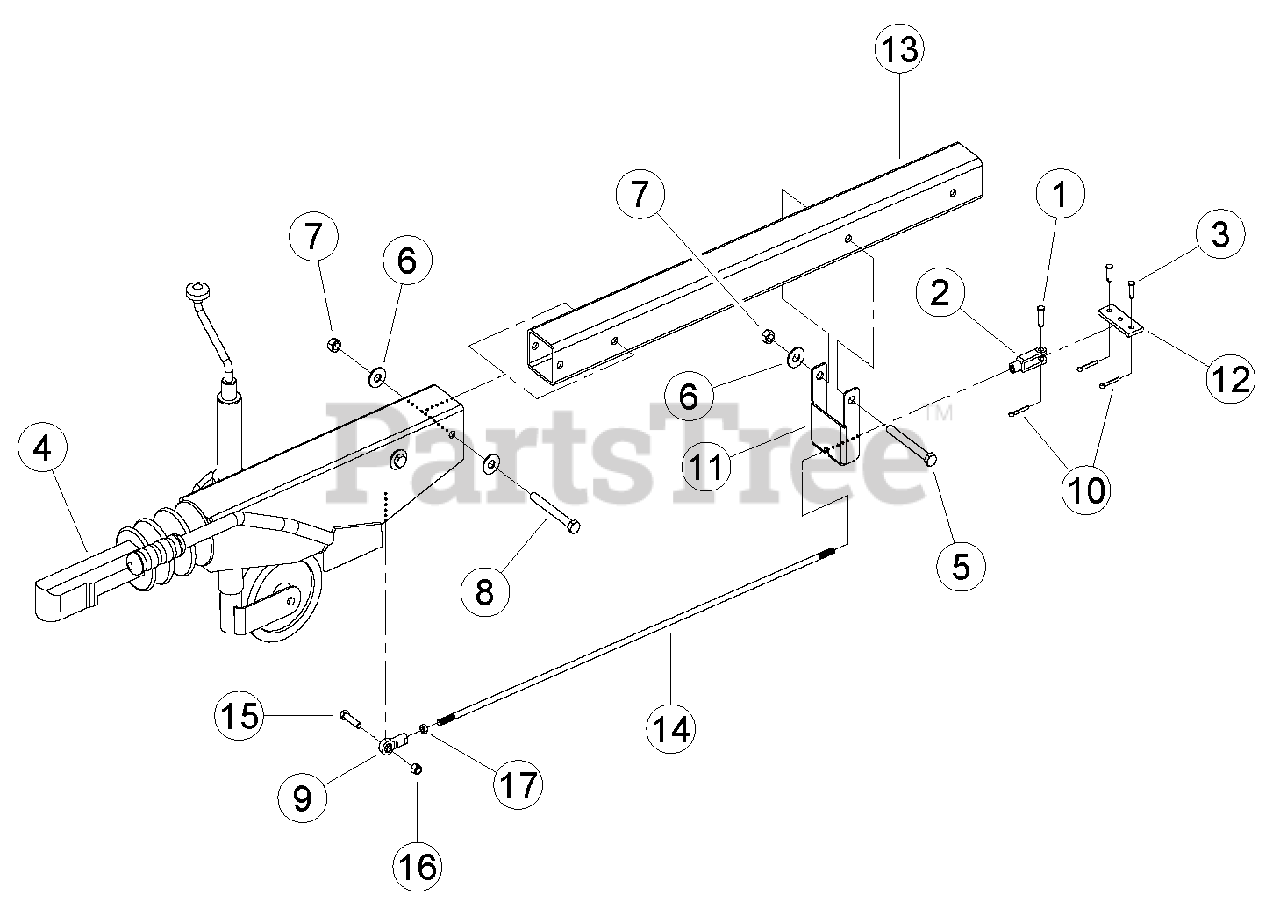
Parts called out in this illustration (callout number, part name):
1	PIN, 3/8 X 1-1/4 CLEVIS ZP
2	CLEVIS, ADJ. ROD END 3/8-24 UNF
3	PIN, 5/16 X 1 CLEVIS
4	COUPLING, SURGE W/JOCKEY WHEEL
5	BOLT, 1/2 X 4-1/2 HEX HD GR5 NC ZP
6	WASHER, 1/2 FLAT ZP
7	NUT, 1/2 CENTERLOCK GRB ZP
8	BOLT, 1/2 X 4 HEX HD GR5 ZP
9	BEARING, 3/8 ROD END
10	PIN, 1/8 X 1.00 COTTER ZP
11	BRACKET, ROD HANGER
12	BAR, BRAKE COMPENSATOR
13	TUBE, CHIPPER HITCH
14	ROD, BRAKE
15	BOLT, 3/8 X 1-1/2 HEX HD GR5 ZP
16	NUT, 3/8 NE NYLOCK ZP
17	NUT, 3/8 NFX
